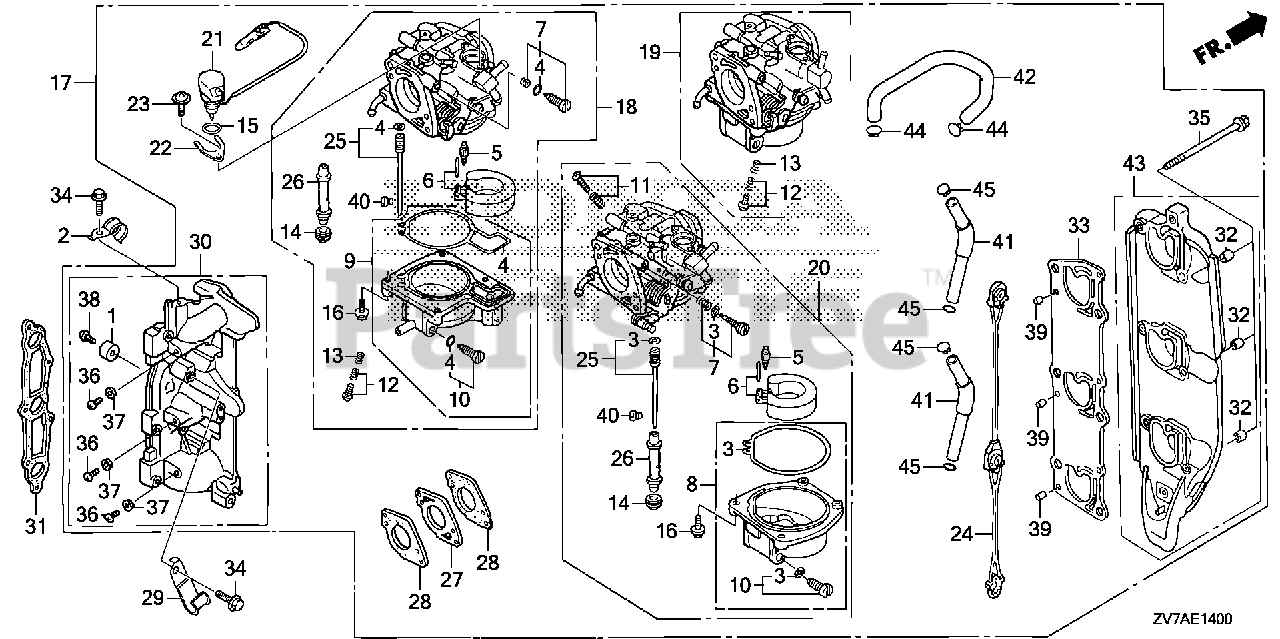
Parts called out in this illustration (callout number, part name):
1	METAL, ANODE
2	CLAMP, TUBE
3	GASKET SET
4	GASKET SET
5	VALVE SET, FLOAT
8	CHAMBER SET, FLOAT
9	CHAMBER SET, FLOAT
10	SCREW SET, DRAIN
13	SPRING, COMPRESSION COIL
14	SCREW, PLUG
15	O-RING, BYSTARTER
16	SCREW-WASHER
17	CARBURETOR ASSY. (BG10C G) *NH8* (DARK GRAY)
18	CARBURETOR ASSY. (#1)
19	CARBURETOR ASSY. (#2)
20	CARBURETOR ASSY. (#3)
21	BYSTARTER ASSY., AUTO
22	PLATE, SETTING
23	SCREW-WASHER
24	LEVER, LINK
25	JET SET (#40)
26	NOZZLE, MAIN
27	INSULATOR, CARBURETOR
28	GASKET, CARBURETOR
29	CLAMP, FUEL TUBE
30	MANIFOLD ASSY., IN. *NH8* (DARK GRAY)
31	GASKET, IN. MANIFOLD
32	COLLAR, DISTANCE
33	GASKET, MUFFLER PLATE
34	BOLT, FLANGE (6X12) (CT200)
35	BOLT, FLANGE (6X97)
36	SCREW, PAN (5X10)
37	WASHER, SEALING (5MM)
38	SCREW, PAN (6X18)
39	ROLLER (6X15)
40	JET, MAIN (#92)
40	JET, MAIN (#98)
42	TUBE, BYSTARTER
43	PLATE, MUFFLER
44	CLIP, TUBE (B10)
45	CLIP, TUBE (B12)
